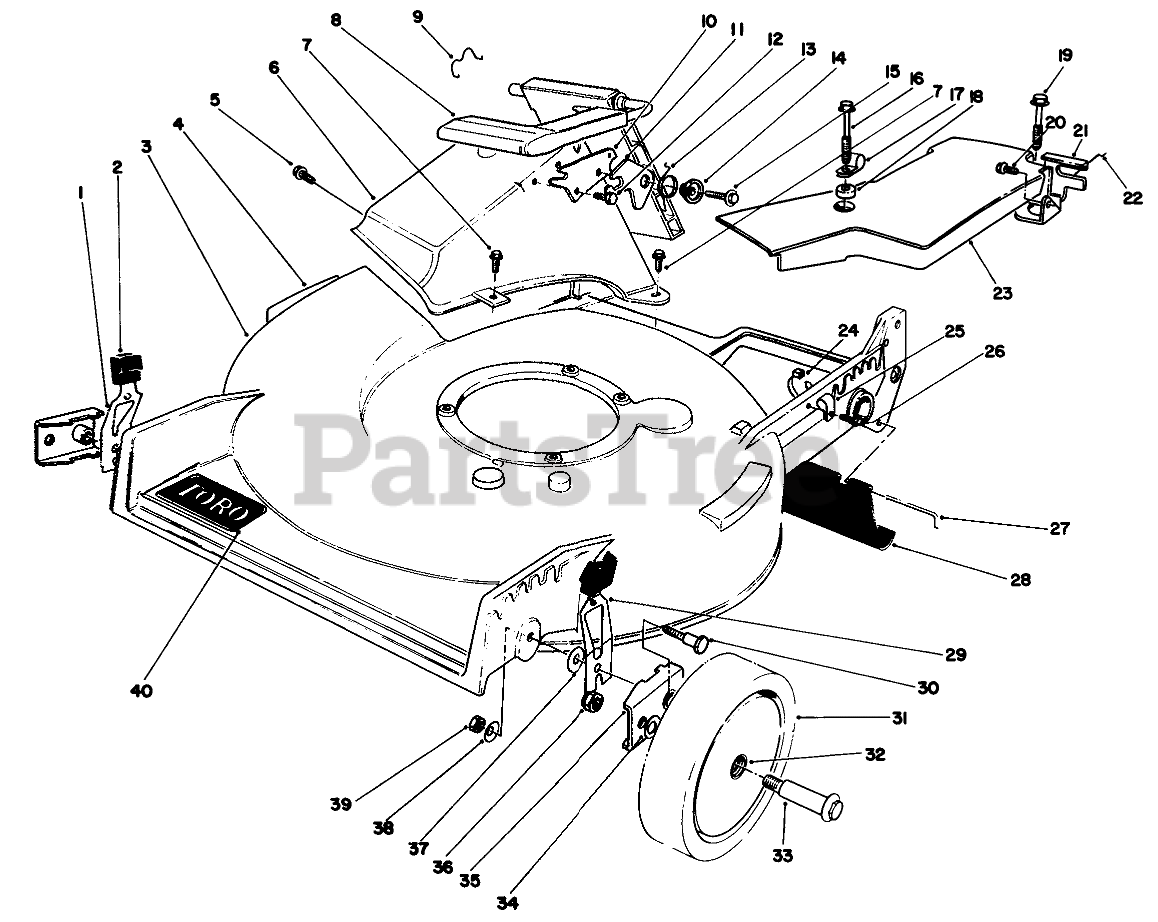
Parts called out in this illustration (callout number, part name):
1	L. HP SPRING ARM ASM
2	KNOB-ARM
3	Housing (Incl. Ref. #4 & 40)
4	DECAL-DANGER
5	SCREW AND WASHER ASM
6	Tunnel Discharge
7	SCREW-HWH
8	Discharge Door Assembly
9	DOOR RET SPRING
10	DOOR LATCH PLATE
11	SAFETY LATCH
12	SCREW-PLASTITE
13	TORSION SPRING
14	DOOR SPACER
15	SCREW-HWH
16	SCREW-SPECIAL
17	CLAMP-CABLE
18	WASHER
19	SCREW-HHFTF
20	SCREW-HWHTF
21	Bracket-Traction Adj.
22	RETAINER-CABLE
23	Cover-Belt
24	TIE-CABLE
25	CLAMP-CABLE
26	SCREW
27	ROD-SHIELD
28	SHIELD-TRAILING
29	R HP SPRING ARM ASM
30	PIVOT SCREW
31	Wheel & Tire Assembly (Incl. Ref. #32)
32	BUSHING
33	WHEEL BOLT
34	WASHER
35	HP PIVOT ARM ASM
36	Nut
37	WASHER-PIVOT
38	WASHER-BELLEVILLE
39	NUT-LOCK, NI
40	DECAL
